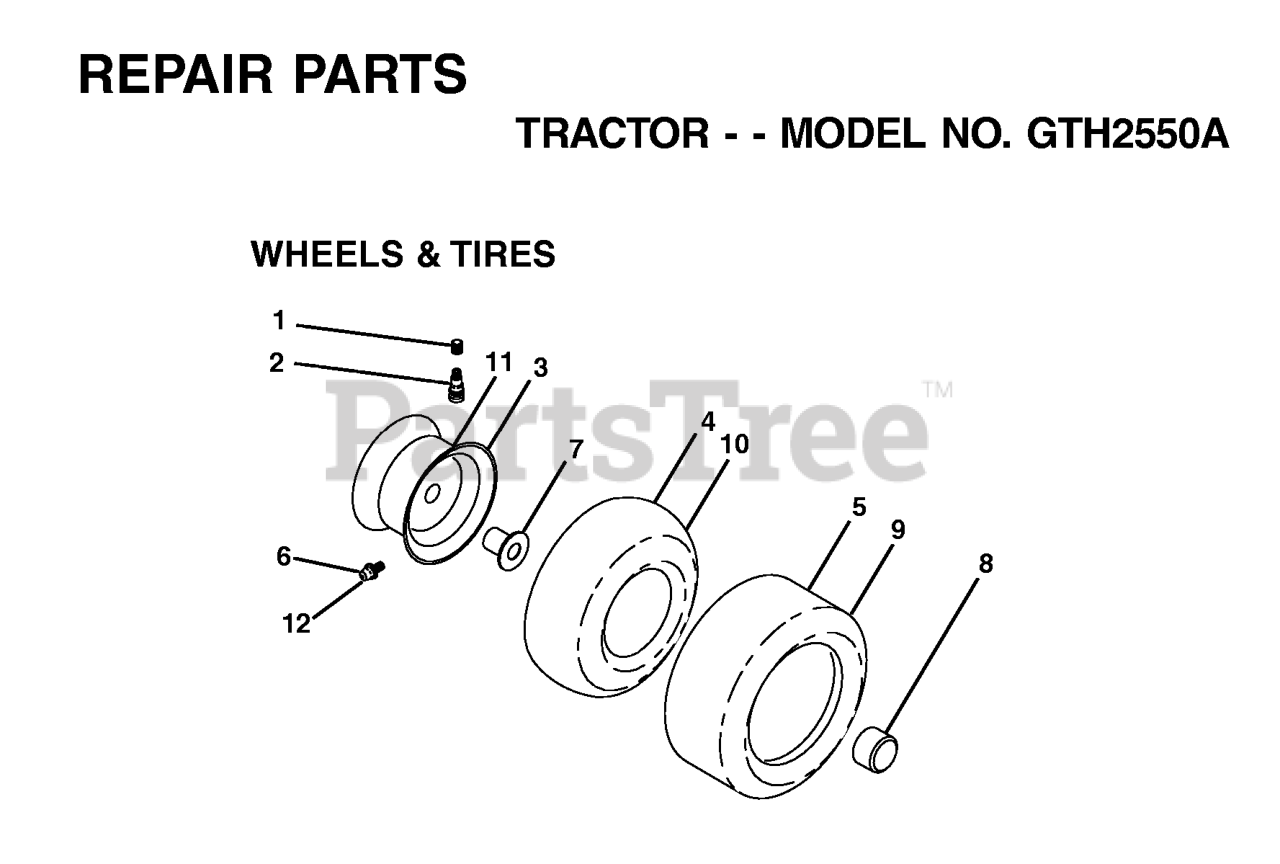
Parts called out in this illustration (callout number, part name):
2	VALVE STEM LT
3	RIM ASSEMBLY, FRONT
4	TUBE.16X6.5/7.5-8
5	TIRE HEAVY DUTY
6	FITTING LT
7	BEARING T
8	CAP, AXLE BLK
9	TIRE HEAVY DUTY
10	TUBE.23X9.5-12
11	RIM.ASM.12X7.REAR.SILVER
12	ZERK FITTING M
